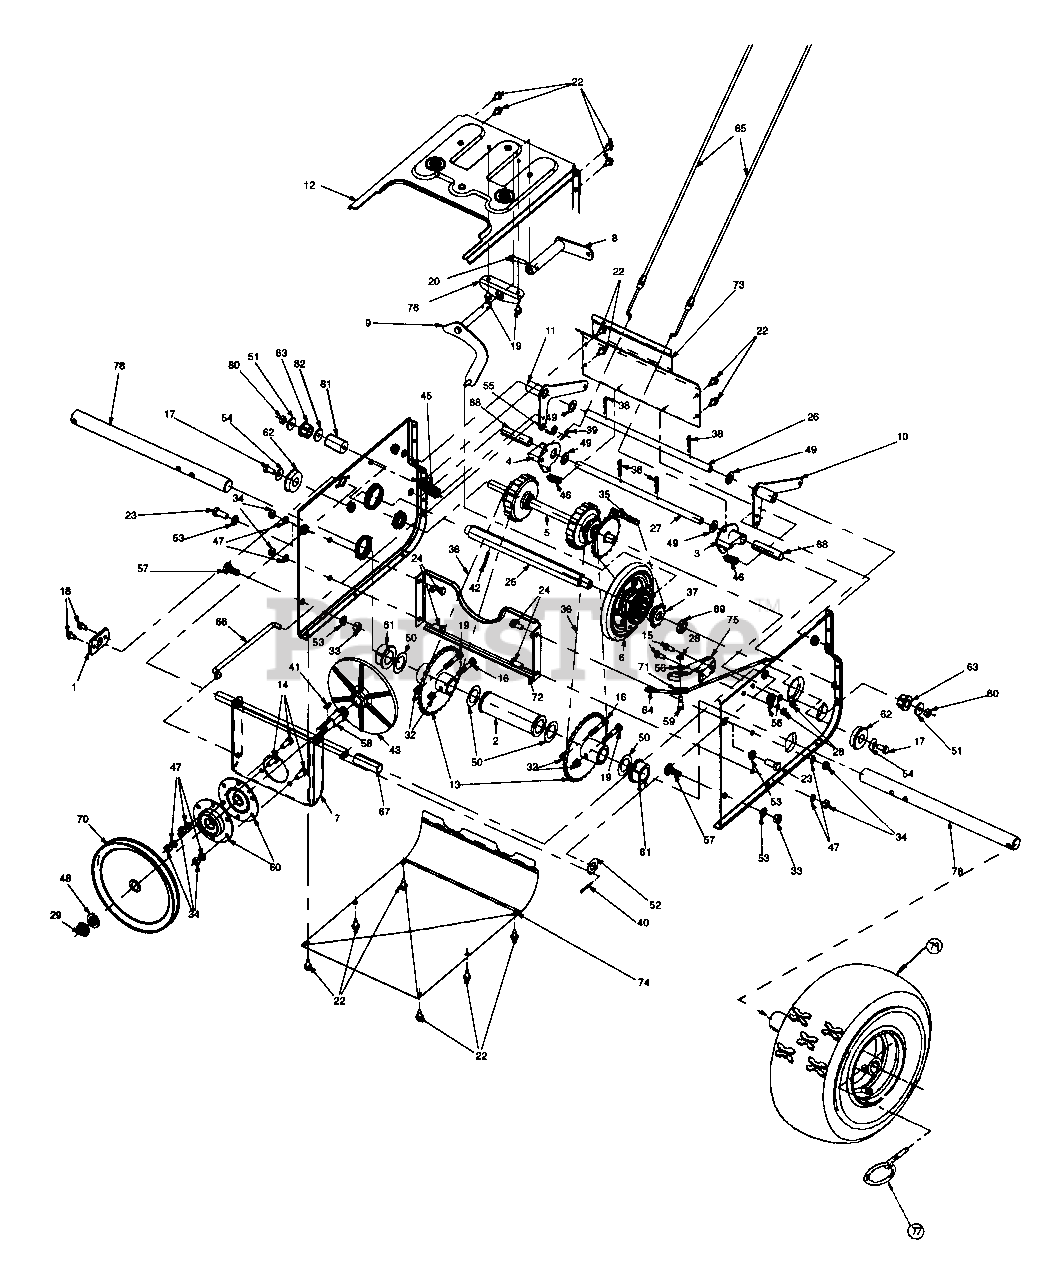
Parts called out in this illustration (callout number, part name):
1	Pivot Axle Brkt..63 Hole - Zinc
2	Bush Asm slev
3	Dogg Asm Dr Lh
4	Dogg Asm Dr Rh
5	Shf Asm Dr
6	Whl Asm Brg 6.0 OD Friction
7	Brkt Asm Supt Friction Dr
10	Brkt Asm Actr Auger
11	Brkt Asm Actr Dr
14	Hex Scr 5/16-18 x .75
15	Hhcs 1/4-28 .625 Gr5 std
16	Hex Scr 5/16-18 x 2.00
17	Hhcs 5/16-18 x .625 Gr5 Lock
18	Scr TT 1/4-20 x .5 Hxindwsh
19	Hex Scr 5/16-18 2.00 Lg
20	Scr Hexwash 1/4-20 x 2.00
22	Scr Ab 1/4-20 .625 Hxindwsh
23	Hhcs 3/8-16 x .880 Gr5 Std
24	Scr Cap 5/16-18x.75Gr5
25	Shf Dr.875 Hex
26	Shf Sctr
27	Shf Actr Dr
28	Hex Nut 1/4-28
29	Hex Ins Jam L-nut 5/8-18
32	Hex Ins L-nut 5/16-18
33	Hex Nut 3/8-16
34	Nut Hex 5/16-18 Gd 5
35	#41 Chain 1/2 Pitch x 36 L
36	#420 Chain 1/2 Pitch x 40 L
37	Spkt 10t #41 x .500
38	Internal Cot-pin 1/2 Dia
39	Intern Cot-pin 5/16 Dia
40	Cotter Pin 1/8 Dia x 1
41	#61 Hi-pro-key 3/16 x 5/8
42	Spring Pin Roll 5/32
43	Aluminum Drive Plate
45	Idler Extension Spring
46	Extension Spring
47	Lock Washer 5/16
48	Lock Washer 5/8
49	Wash F1.531 ID x.930 OD x.05
50	Wash Fl 1.03 ID x 1.62 OD
51	Wash Fit 1/4 ID x .930 OD x.12
52	Wash Flt .640 ID x 1.24 OD x .06 1
53	Lock Washer 3/8 Heavy
54	Bell Wash .345 ID x .88 OD
55	Fl-wash Sae .34 x.68.062
56	Lock Washer 1/4
57	Shld Scr .498 Dia x .340
58	Drive Plate Spindle
59	Scr Shldr .340 D. 1/4 Ab
60	Asm Brg Hsg
61	Flange Brg Pm W/flts 1.0
62	Ball Bearing W/snap Ring
63	Brg Hex Flange x.564 ID
64	Cb Idlr Auger
65	Cbl Strg
66	Rod Clu Dr
67	Spcr Spit .64 x .77 x 2.1
68	Split Spacer 1/2 x 5/8 x 2.44
69	Spcr .675 ID x 1.00 OD x .23
70	1/2 V-pulley .62 ID x 7.5
71	Cable Guide Roller
72	Brkt Supt Frm
77	Klik Pin Assy Danuse
78	Axle 1.0 OD x 14.1 Lg
80	Jam L-Nut 3/8-24 Thd.
81	Spacer
82	Fl-Washer
